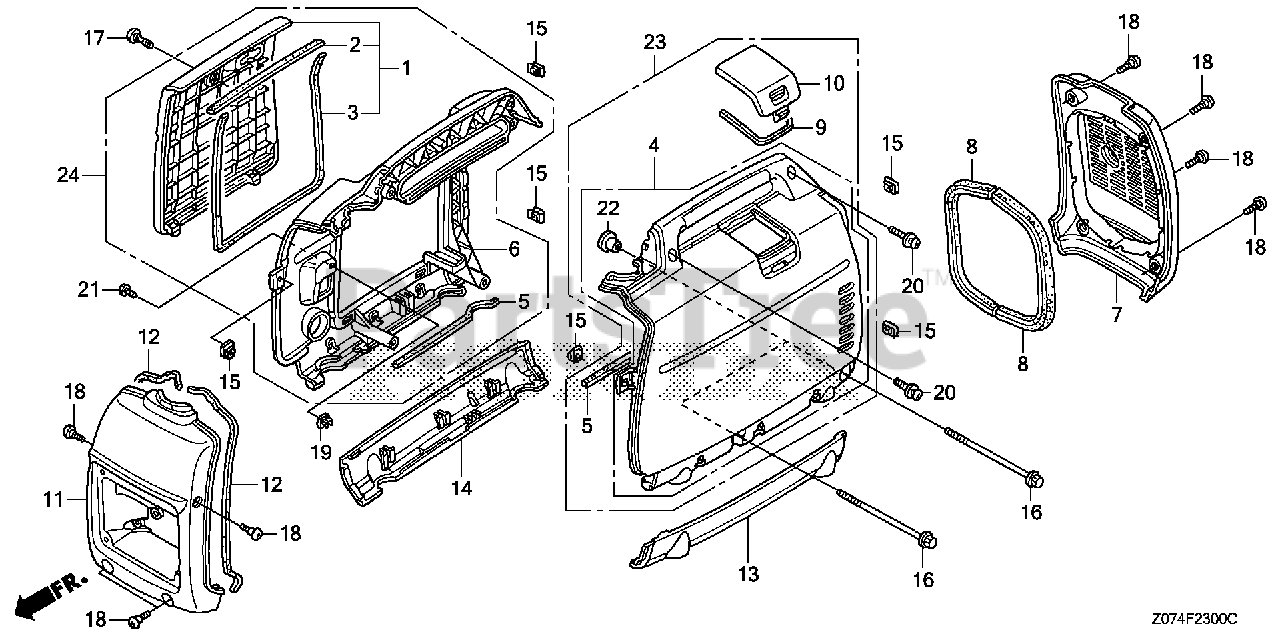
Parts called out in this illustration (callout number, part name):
1	COVER ASSY., MAINTENANCE *YRA09L* (REAL CAMO GREEN)
2	SEAL A, MAINTENANCE COVER
3	SEAL B, MAINTENANCE COVER
4	COVER, SIDE *YRA09L* (REAL CAMO GREEN) (L. SIDE)
5	SEAL A, SIDE COVER
6	COVER, SIDE *YRA09L* (REAL CAMO GREEN) (R. SIDE)
7	COVER, RR. *NH314* (CONDUCT GRAY)
8	RUBBER, RR. COVER SEAL
9	SEAL, PLUG CHECK
10	COVER, PLUG CHECK *YRA09L* (REAL CAMO GREEN)
11	COVER, FR. *NH314* (CONDUCT GRAY)
12	SEAL, FR. COVER
13	PLATE, SIDE (LOWER) *NH314* (CONDUCT GRAY) (L. SIDE)
14	PLATE, SIDE (LOWER) *NH314* (CONDUCT GRAY) (R. SIDE)
15	NUT, FENDER SETTING
16	BOLT, FLANGE (6X137)
17	SCREW, SPECIAL (6X16)
18	SCREW, SPECIAL (6X15)
19	GROMMET, SCREW (6MM)
20	SCREW-WASHER (6X20)
21	SCREW, TAPPING (5X16) (PO)
22	COLLAR, FAN COVER
23	COVER KIT, SIDE *YRA09L* (REAL CAMO GREEN) (LEFT HAND SIDE)
24	COVER KIT, SIDE *YRA09L* (REAL CAMO GREEN) (RIGHT HAND SIDE)
